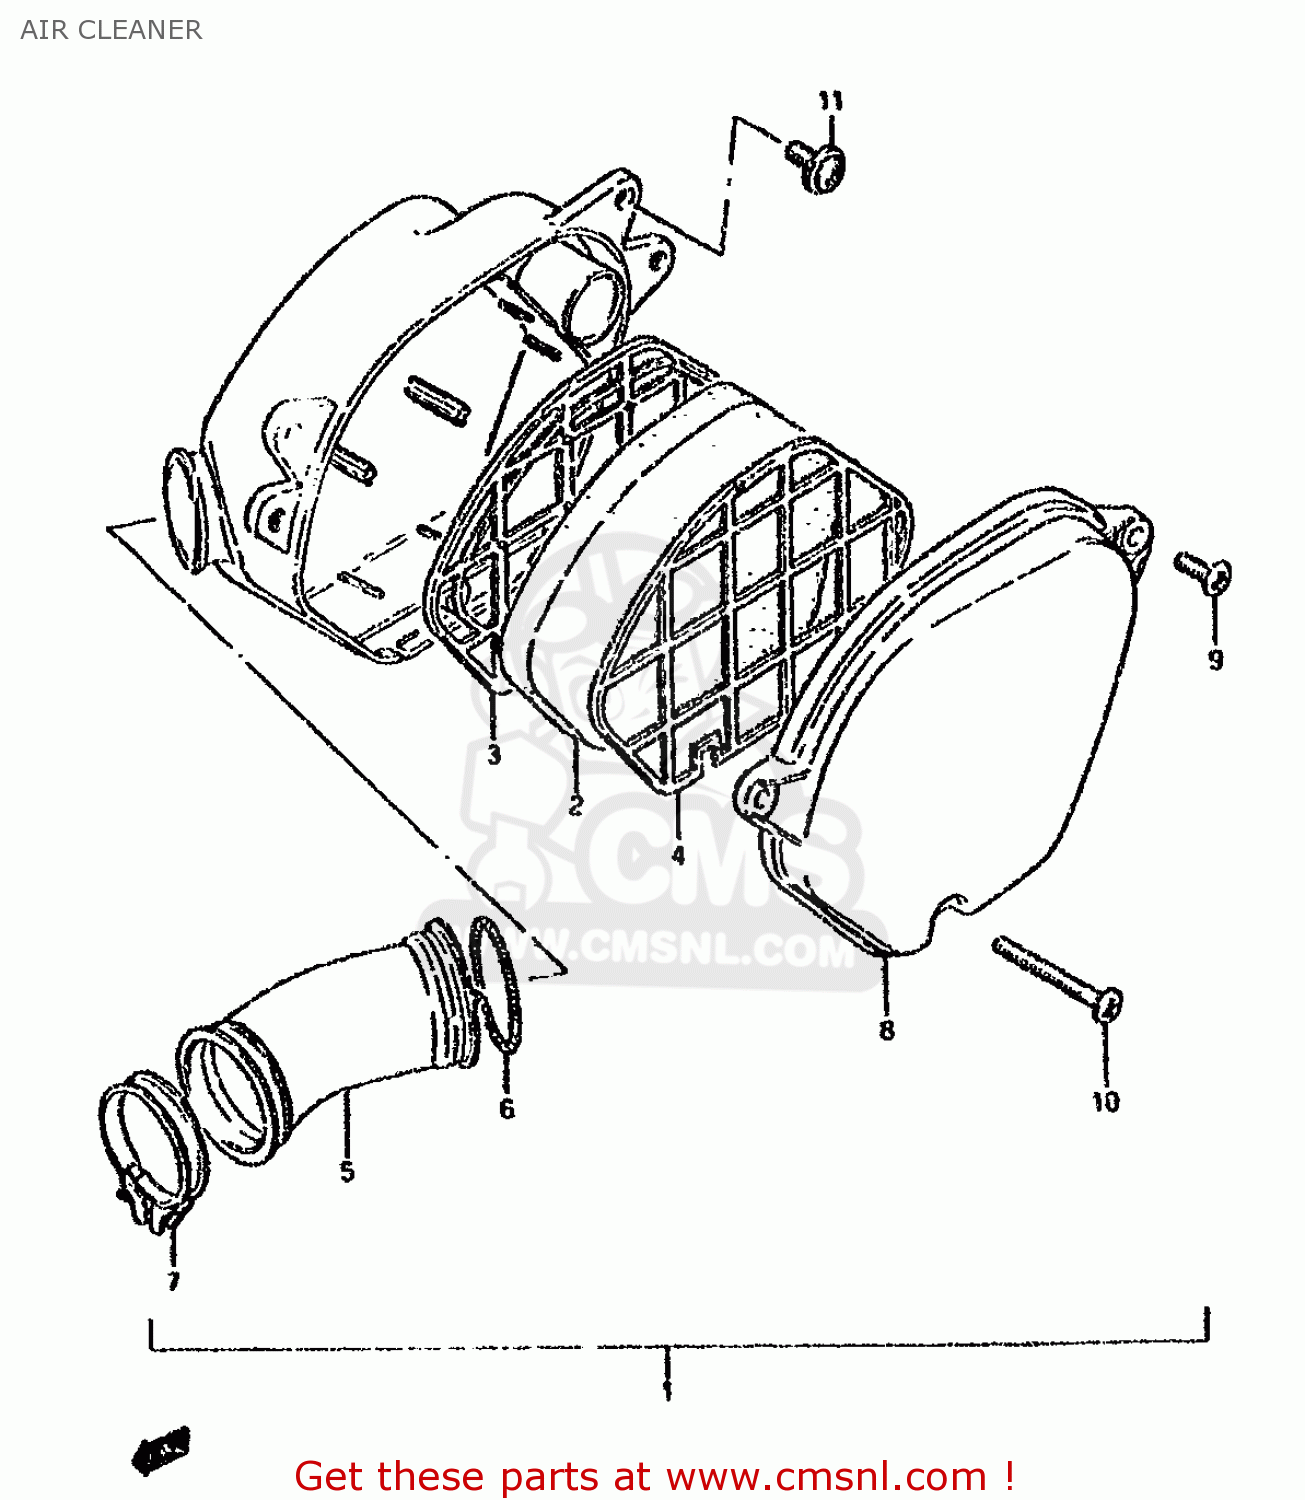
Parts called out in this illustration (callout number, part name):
1	CLEANER ASSY,AIR
2	FILTER
3	HOLDER,FILTER INNER
4	HOLDER,FILTER OUTER
5	TUBE,OUTLET
6	SPRING,AIR CLEANER SIDE
7	CLAMP
8	CAP,CLEANER
9	SCREW
10	SCREW
11	SCREW(6X16)
